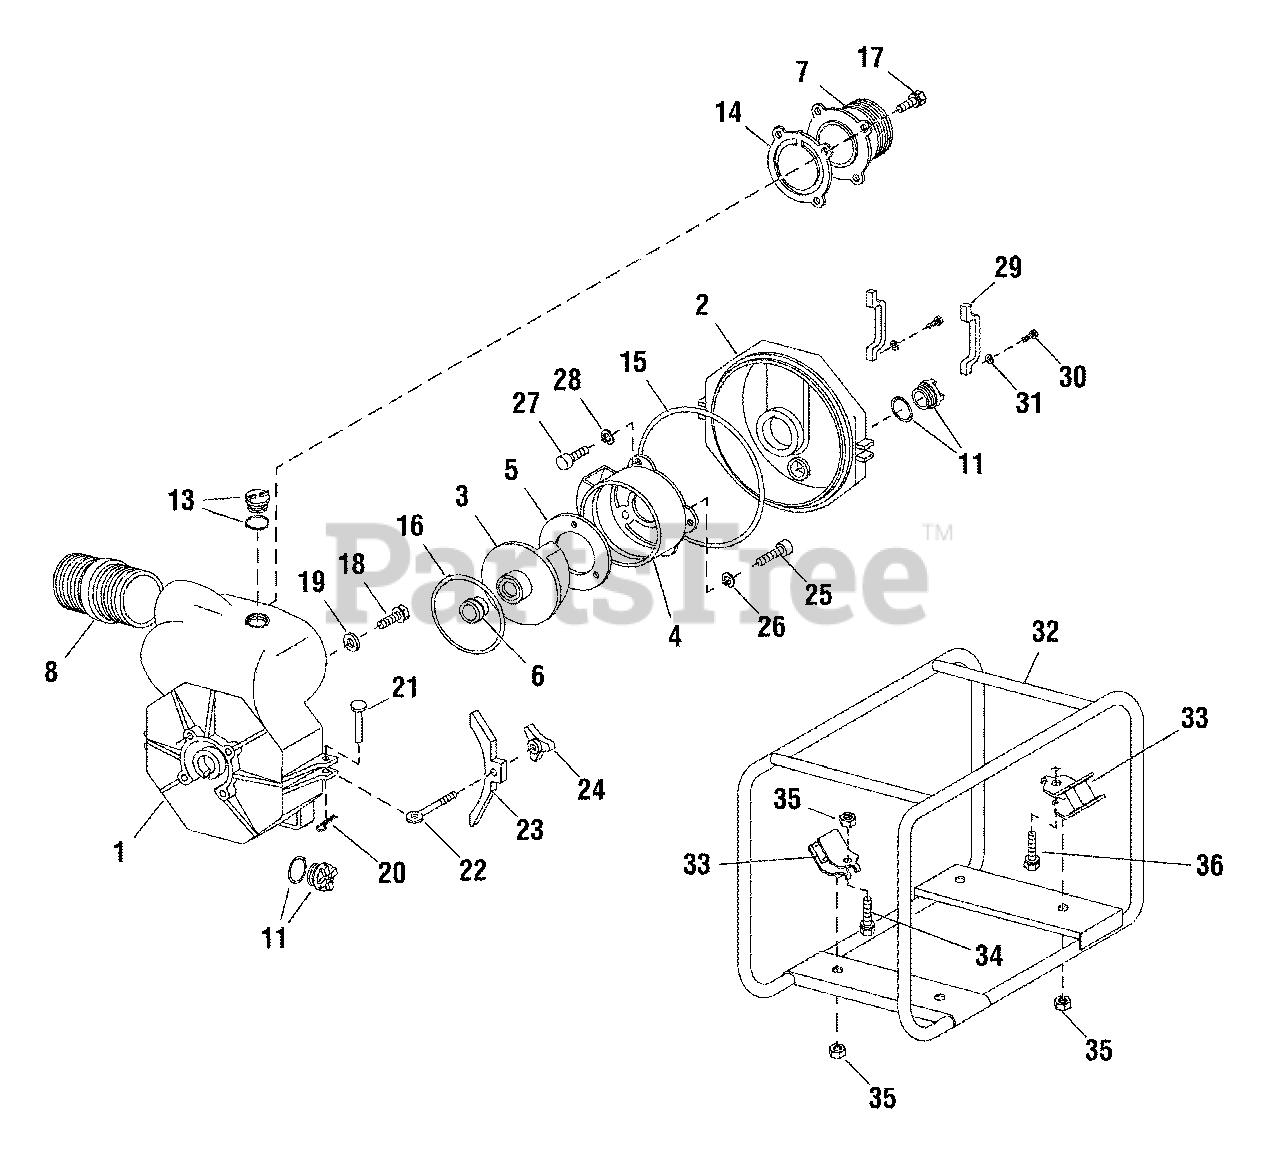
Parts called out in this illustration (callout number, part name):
7	ADAPTER, Hose, 2" NPT
8	FITTING, 2" NPT
17	* BOLT, M8 x 25
18	* BOLT, Flange, M8 x 50
25	* BOLT, Hex Socket, M6 x 16
26	* WASHER, Lock, M6
27	* BOLT, Hex Socket, M8 x 20
28	* WASHER, Lock, M8
30	* BOLT, M6 x 25
31	* WASHER, M6
33	MOUNT, Vibration
34	* BOLT, M8 x 40
35	* NUT, Flange, M8
36	* BOLT, M8 x 20
